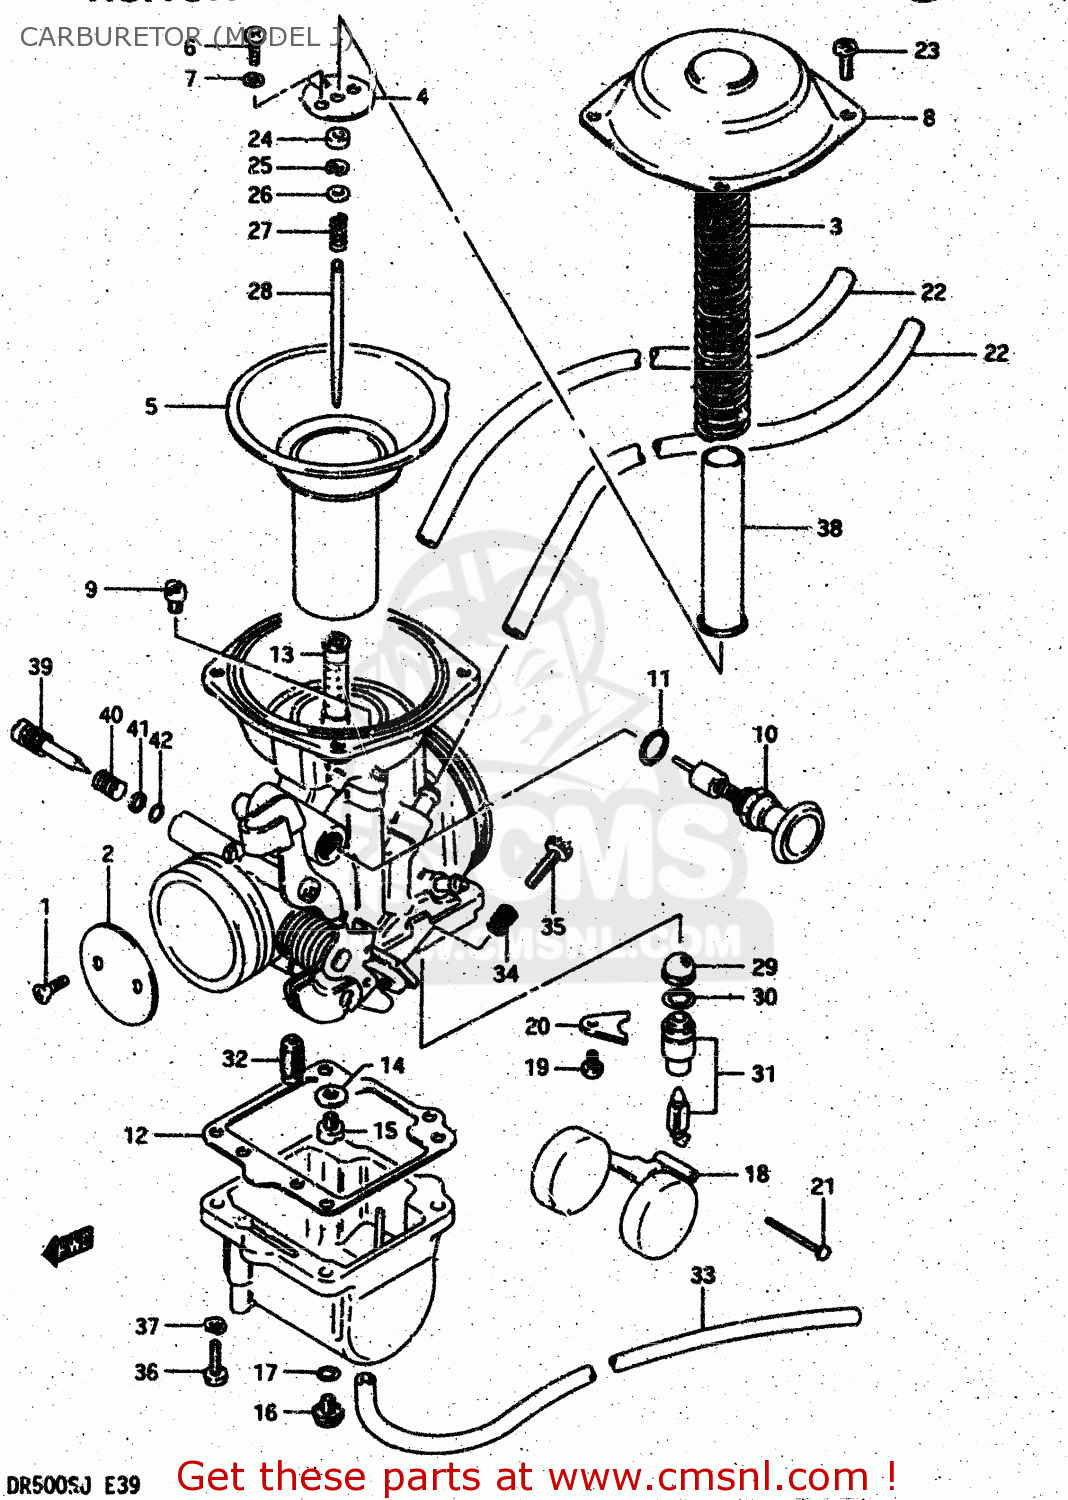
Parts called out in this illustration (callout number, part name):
1	SCREW
2	VALVE,THROTTLE (BUTTERFLY)
3	SPRING,DIAPHRAGM
4	PLATE
5	DIAPHRAGM ASSY
6	SCREW
7	LOCK WASHER
8	COVER
9	JET,MAIN(105)
10	PLANGER ASSY
11	O RING
12	GASKET,FLOAT CHAMBER (NAS)
13	JET, NEEDLE (X-2)
14	WASHER,NEEDLE NOZZLE
15	JET,MAIN(142.5)
16	PLUG,DRAIN
17	GASKET (NAS)
18	FLOAT
19	SCREW
20	PLATE
21	PIN,FLOAT
22	HOSE
23	SCREW 5X10
24	RING
25	CLIP,NEEDLE
26	WASHER
27	SPRING
28	NEEDLE JET
29	FILTER
30	O-RING,NEEDLE VALVE
31	VALVE ASSEMBLY,NEEDLE
32	JET,PILOT(47.5)
33	HOSE
34	SPRING
35	SCREW,THROTTLE STOP
36	SCREW
37	LOCK WASHER
38	PIPE
39	SCREW,AIR
40	SPRING
41	WASHER
42	O RING,PILOT AIR SCREW
